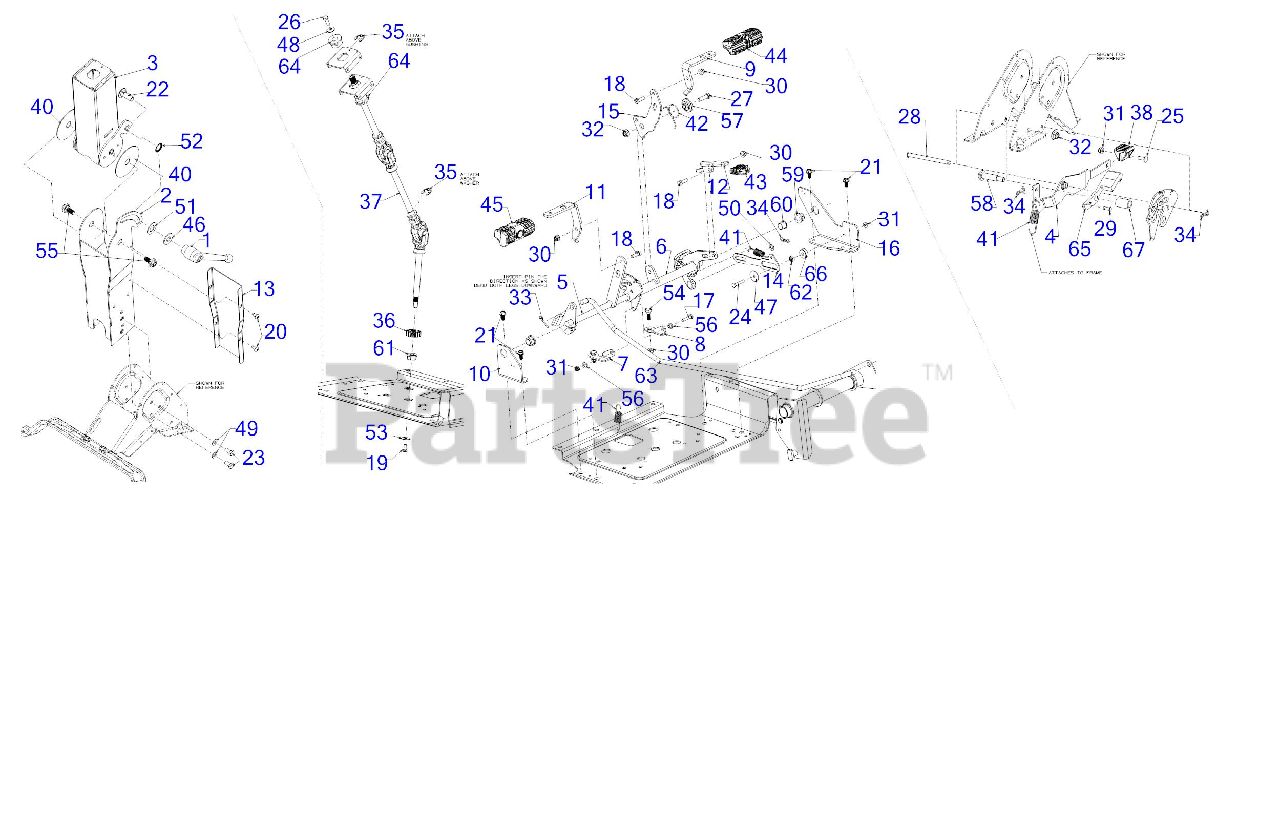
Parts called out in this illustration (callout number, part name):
1	STEERING COLUMN ADJUST LEVER
5	BRAKE SHAFT ASSEMBLY
6	DRIVE PEDAL ASSEMBLY
14	NEUTRAL RETURN LINK
15	FORWARD PEDAL BRACKET
17	HEX SCREW 1/4-20 x 1.25
18	SCREW 5/16-18 x 1.0 GR5
19	SCREW 1/4-20 x .62 SPEC GR5
20	SCREW 1/4-20 x .500
21	SCREW 5/16-18 x .750
22	CARRIAGE BOLT 1/2-13 x 1.25 GR5
23	SCREW 5/16-18 x .62 GR5
24	SCREW 1/4-20 x 1.50 GR.5
25	SCREW 1/4-20 x .75 GR5
26	SCREW 5/16-24 x .875 GR5
27	SCREW 3/8-16 x 1.25 GR5
28	CLEVIS PIN 5/16 x 4.135
29	CLEVIS PIN .224 x .625
30	FLANGE LOCK NUT 5/16-18
31	FLANGE LOCK NUT
33	COTTER PIN-5/32 DIA
34	BOW TIE COTTER PIN 1/4-5/16
35	E-RING
36	STEERING GEAR 14T
37	COMPLETE STEERING SHAFT
37	FLANGE BEARING
37	FLAT WASHER
38	CRUISE TILT KNOB
40	COLUMN PLATE
41	EXTENSION SPRING
42	TORSION SPRING
43	REVERSE PEDAL PAD
44	FORWARD PEDAL PAD
45	BRAKE PEDAL PAD
46	FLAT WASHER
47	FLAT WASHER
48	BELL WASHER .337 X.867 x .057
49	FLAT WASHER
50	WASHER THRUST .375X.70X.030
51	FLAT WASHER NYLON 5/8
52	LOCK WASHER
53	FLAT WASHER
54	SHOULDER SCREW .437
55	SHOULDER SCREW .625X.165X3/8-16
56	SHOULDER SPACER
57	SHOULDER SPACER 1.50X.38X.38
58	SHOULDER SCREW .496X1.44 3/8-16
59	FLANGE BEARING
60	NYLINER BEARING
61	FLANGE BEARING
62	BALL BEARING .25 X .625
63	FRONT BRAKE ROD
64	FLANGE BEARING
65	CRUISE LATCH
66	SPACER .267X1.00X.36
67	SPACER 0.510 X 0.775 X 1.190
